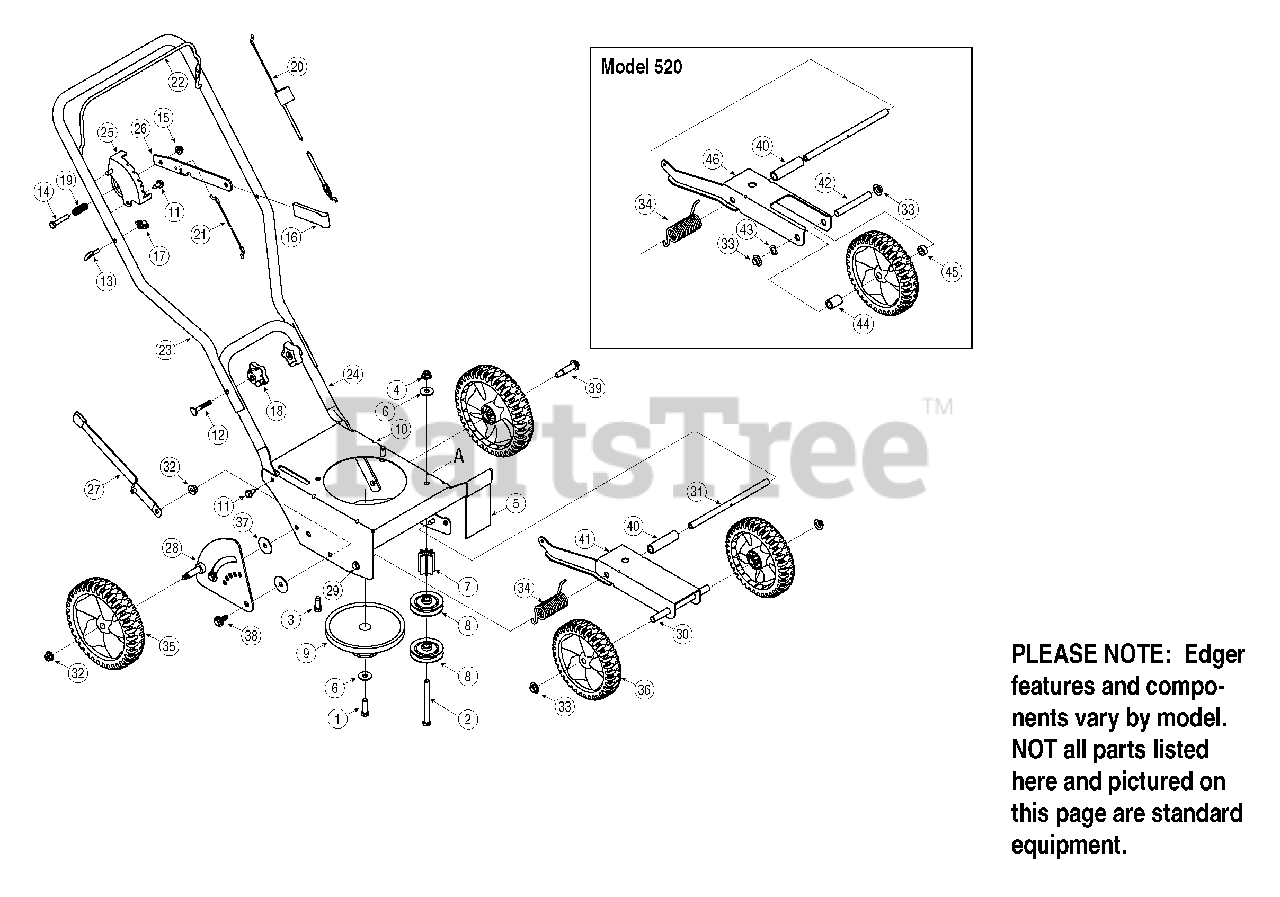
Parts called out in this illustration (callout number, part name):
1	Screw 3/8-24
2	Screw 3/8-16
3	Screw, 3/8-16
4	Flange Lock Nut, 3/8-16
5	Debris Guard
6	Bell Washer, .396 x 1.140
7	Pulley Mount Spacer
8	Flat Idler Pulley, 2.5 OD
9	Combination Flywheel
12	Carriage Bolt, 5/16-18
13	Rope Guide (Eye Bolt)
14	Hex Screw, 5/16-18
15	Lock Flange Nut, 5/16-18
17	Wing Nut
18	Hand Knob
19	Compression Spring
20	Control Cable (Briggs & Stratton)
21	Wheel Adjustment Cable
24	Threaded Frame Spacer
27	Curb Height Adjustment
28	Curb Height Adjuster Plate
29	Hex Screw 5/16-18 x .625
30	Axle Shaft .50x6.65
31	Frame Spacer .50x9.25
32	Flange Nut 3/8-16
33	Push Cap 1/2" rod
34	Torsion Spring
35	Wheel 8x1.8
36	Wheel 7x1.8
37	Flat Washer, .385 x 1.5 x .075
38	Shoulder Screw, 3/8-16
39	Shoulder Screw, 3/8-16
40	Spacer
42	Spacer
43	Wave Washer
44	Spacer, .525 x .775 x .1125
45	Spacer, .525 x .775 x .3125
